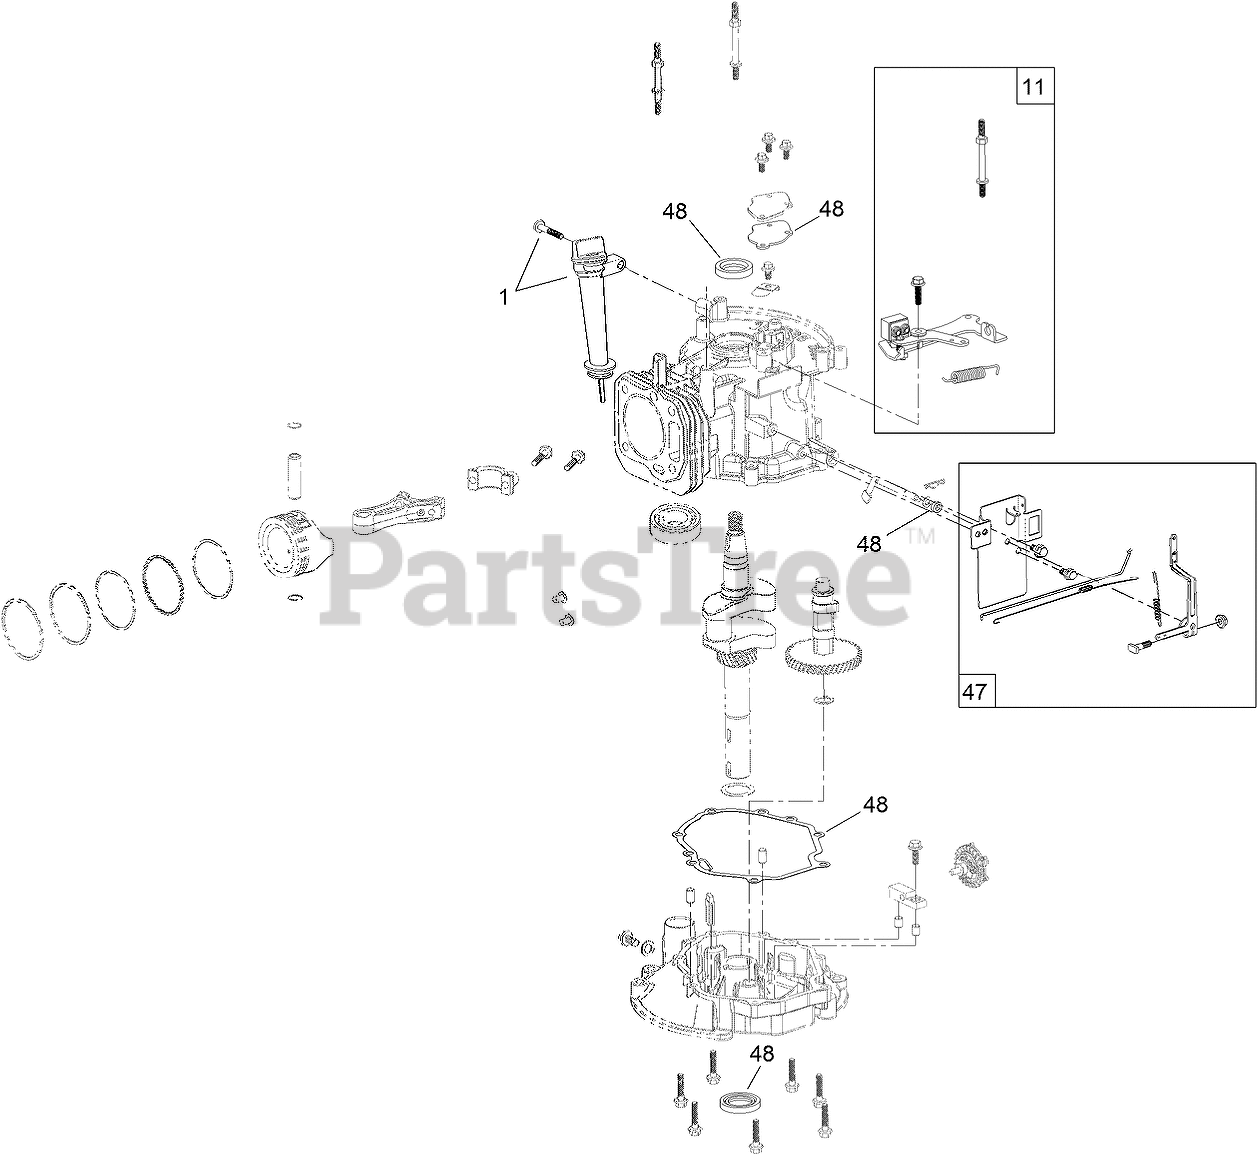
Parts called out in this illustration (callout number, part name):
1	DIPSTICK AND FILL TUBE KIT
11	BRAKE KIT
47	GOVERNOR ARM KIT
48	SEAL AND GASKET KIT
